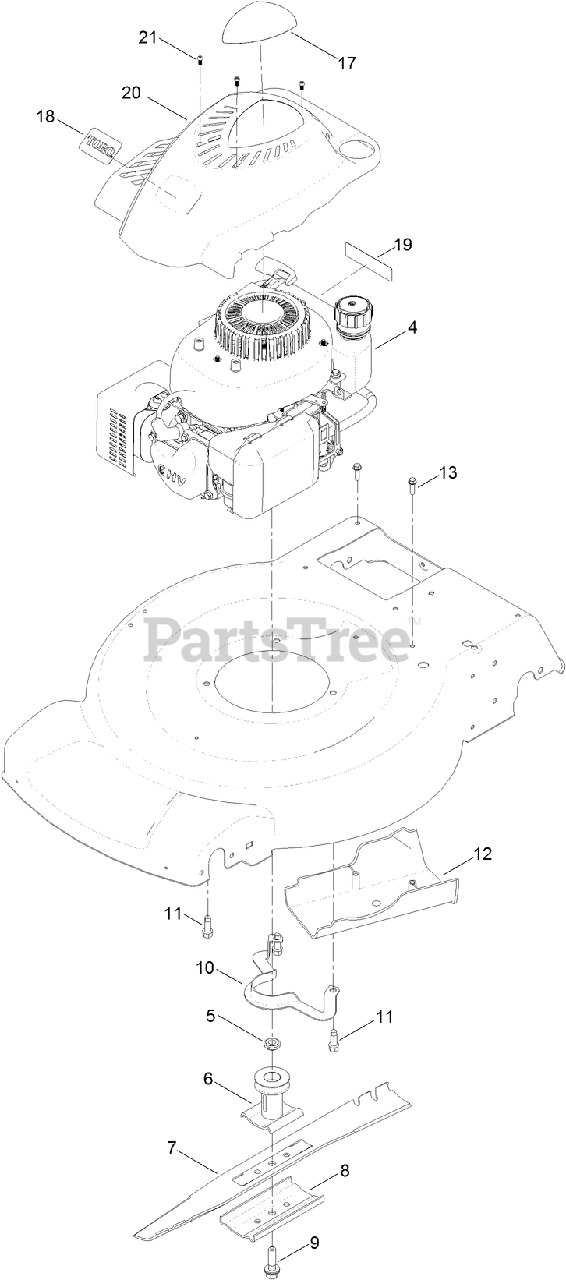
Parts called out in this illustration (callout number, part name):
5	SPACER-DRIVER
6	DRIVER-BLADE
8	SUPPORT-BLADE
9	BOLT-BLADE
10	GUIDE-BELT
11	SCREW-TAPTITE
12	COVER-BELT
13	SCREW-HWH
17	DECAL-SHROUD
19	DECAL-ARRESTER, SPARK
20	SHROUD
21	SCREW-PPH
